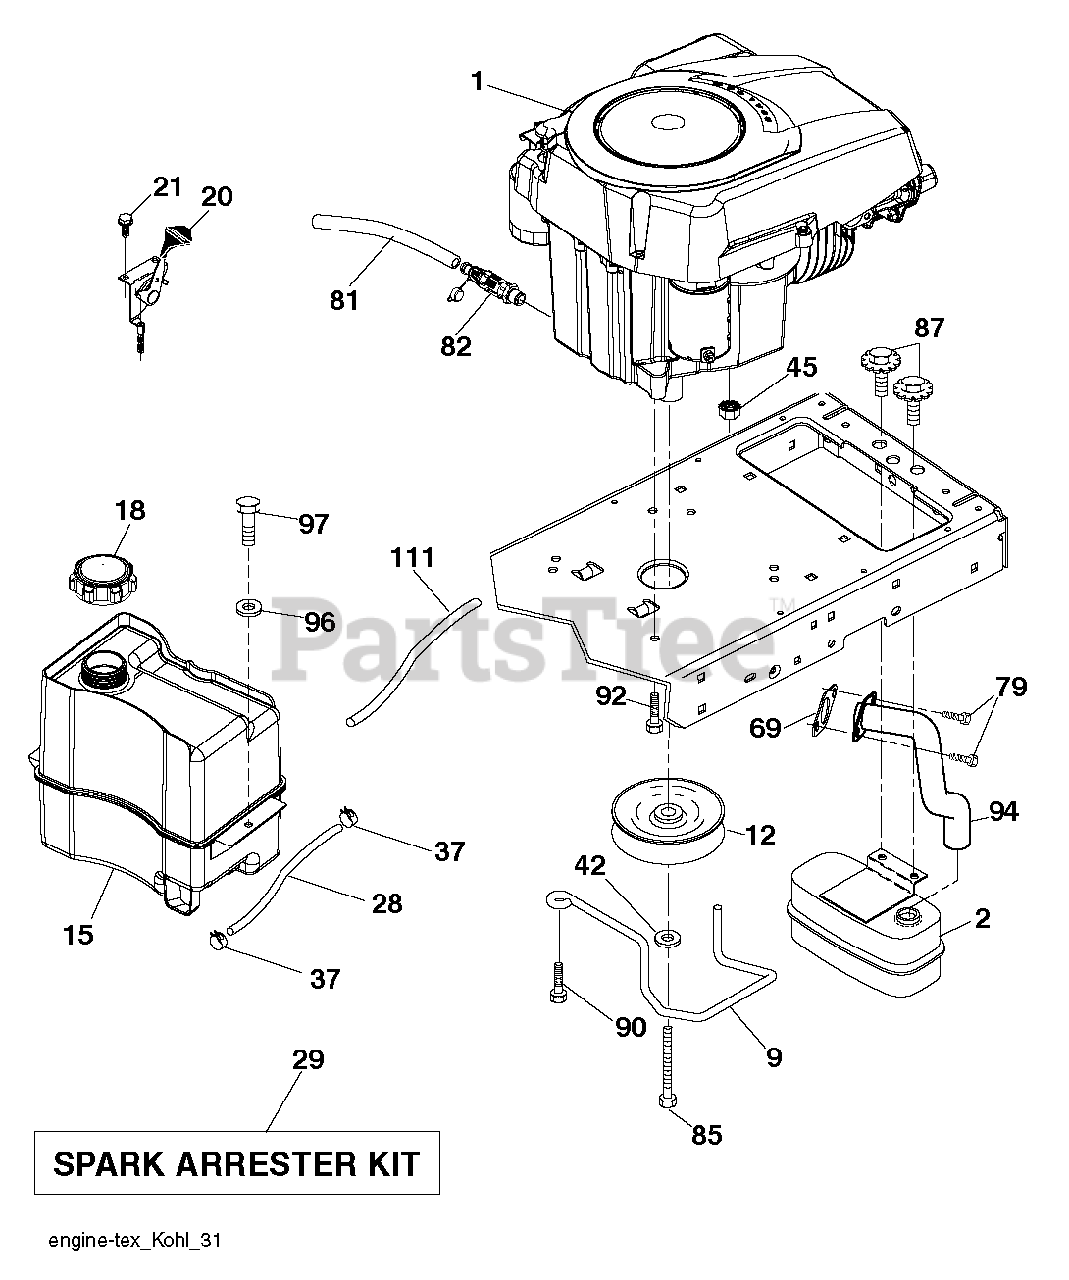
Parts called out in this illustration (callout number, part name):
1	Husqvarna TBD
2	MUFFLER.SINGLE.CYL.KOHL/B&S
9	KEEPER.BELT.ENGINE.4.2
12	PULLEY ENGINE
15	TANK.ASM.FUEL.FR.2.5GA.
18	CAP.2.25'.VENTED.TETHER .EPA
20	CONTROL.TH/CK.COBRA.KO
21	SCREW.#10 X 0.750.BOS
28	LINE.FUEL.20"FRONT.EMI
29	KIT.SPARK ARRESTOR 794945 B&S
37	HOSE CLAMP
42	LOCKWASHER
45	NUT
69	GASKET.EXHAUST.KOHLER
79	SCREW.SOCKET HD.5/16-1
81	TUBE, DRAIN OIL ASM.
82	VALUE.OIL.DRAIN
85	BOLT HEX 7/16-20X4-1/4"
87	Bolt, 5/16-18 X 1-3/4
90	SCREW 3/8-16X1
92	SCREW 3/8-16X1
94	RP.TUBE.EXHAUST.KOHL.COURAGE
97	SCREW HEXWSHR 1/4-20X3/4
111	RP PURGE LINE
